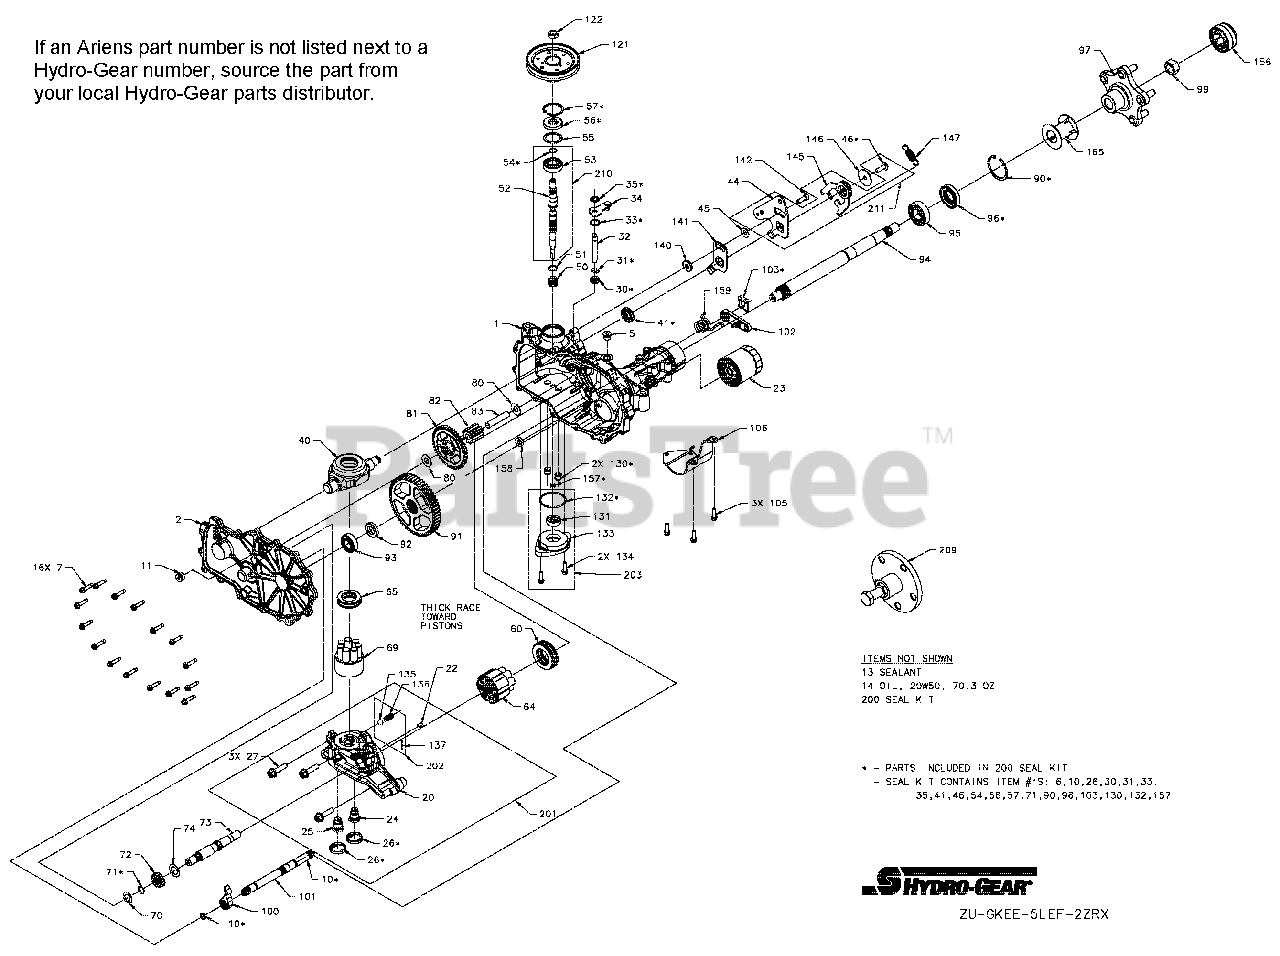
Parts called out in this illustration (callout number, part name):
7	HFHCS 1/4-20 x 1.125"
13	SEALANT
22	PLATE, BYPASS
23	FILTER, OIL
26	SEAL, PLUG 1.250 x .250
30	SEAL, LIP .375 x .75 x .25
31	RING, RET .375 EXTRNL
33	RING, RET .750 INTRNL
34	ARM, BYPASS
35	RING, RTNG .375 EXT
40	TRUNNION, SWASHPLATE
41	SEAL, LIP 12 x 32 x 7
45	WASHER .34 x .88 x .06
46	TWHCS 5/16-24 x 1.00 (PATCH)
50	SPRING, BLOCK
51	WASHER-FLAT .59 x .79 x .04
55	WASHER 1.23 x 1.56 x .04
56	SEAL, LIP 17 x 40 x 7
57	RING, RETAINING
60	BEARING, THRUST
64	ASS'Y, CYLINDER BLOCK, 16cc
65	BRG, THRUST PLASTIC CAGE
69	ASS'Y, BLOCK 7 PISTON
70	WASHER .63 x 1.0 x .05
71	RING, RETAINING_.625
74	WASHER .72 x 1.16 x .04
80	WASHER .5 x 1.0 x .03
83	JACK SHAFT (PIN)
90	RING, RET 2.06 INT
95	BRG, BALL 25.4 x 52 x 15
96	SEAL, LIP 1.000 x 2.049 x .375
97	KIT, HUB, 5 BOLT
99	NUT, HEX LOCK 3/4-16
102	KIT, HANDLE, ACTUATING
103	CLIP, RETAINING
121	PULLEY, 4.5 x 1.625
122	NUT,HEX JAM 1/2-20 W/ PATCH
131	GEROTOR ASSEMBLY (1.9 cc/rev)
132	O-RING, -137, 0.103 x 2.050
140	SPACER .320 x 1.005 x .179
141	ARM, NEUTRAL RIGHT
142	SHCS 5/16-24 x 1 PATCH
146	WASHER, .343 x 1.500 x .062
147	SPRING, EXTNSN RTN-34LBS
157	SEAL, LIP 8 x 12 x 3 VC
158	MAGNET, RING
159	SPRING, TORSION CCW
200	KIT, SEAL
201	KIT, CENTER SECTION, RH, CHRG
203	KIT, CHARGE PUMP
210	KIT, INPUT SHAFT
211	KIT, RTN, CW
